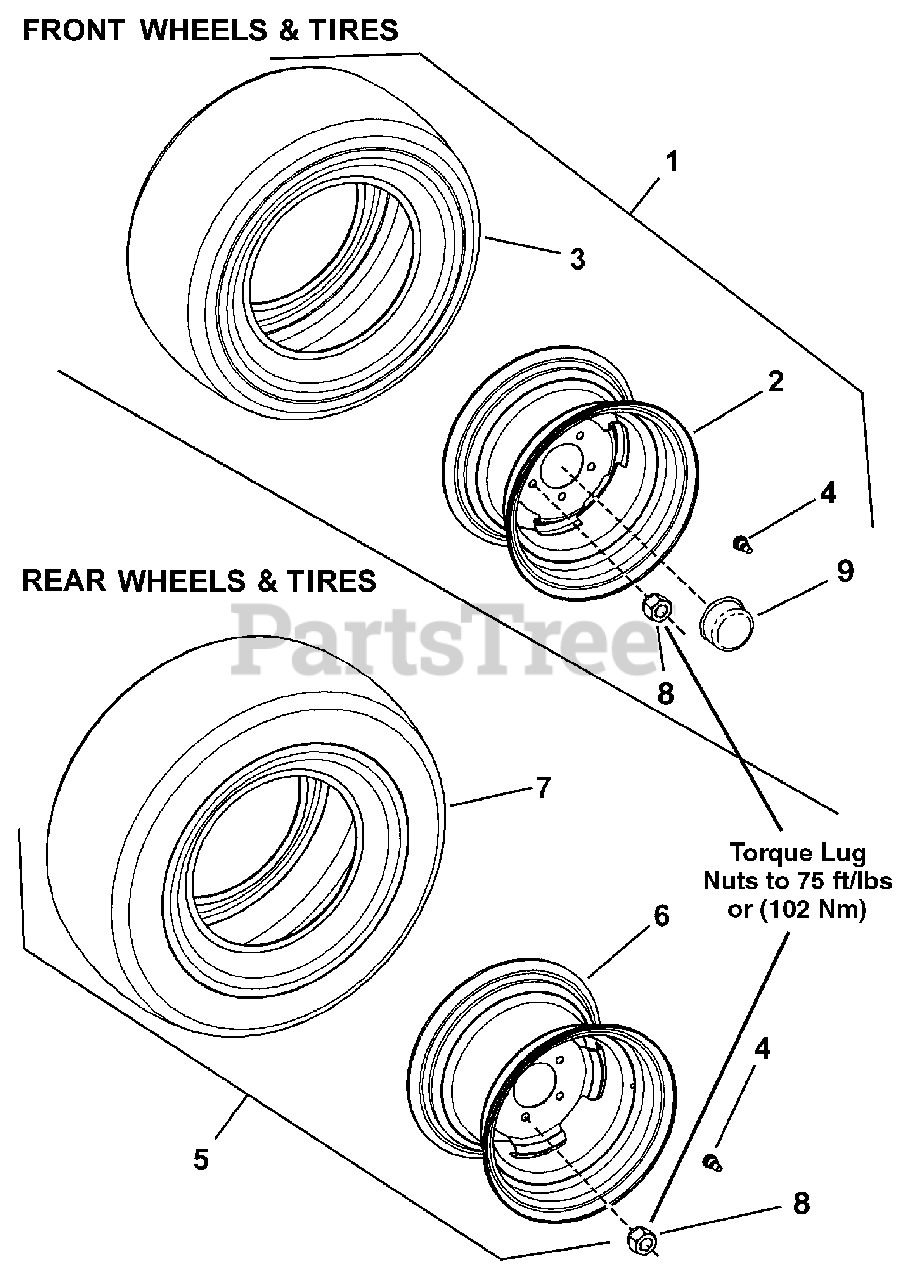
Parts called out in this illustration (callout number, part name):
1	ASSEMBLY, Front Wheel, Turf Tire (Includes Ref. Nos. 2, 3 & 4)
2	RIM, 12 x 7.00 w/ 1.06 Inset
3	TIRE, Titan Multi Trac C/S, 23 x 8.50-12
4	AIR VALVE (Snap-In)
5	ASSEMBLY, Rear Wheel, Turf Tire (Includes Ref. Nos. 4, 6 & 7)
6	RIM, 12 x 8.50 w/ .95 Offset
7	TIRE, Titan Multi Trac C/S, 26 x 12.00-12, 4P
8	LUG NUT, 1/2-20 Tapered Seat
9	DUST CAP
